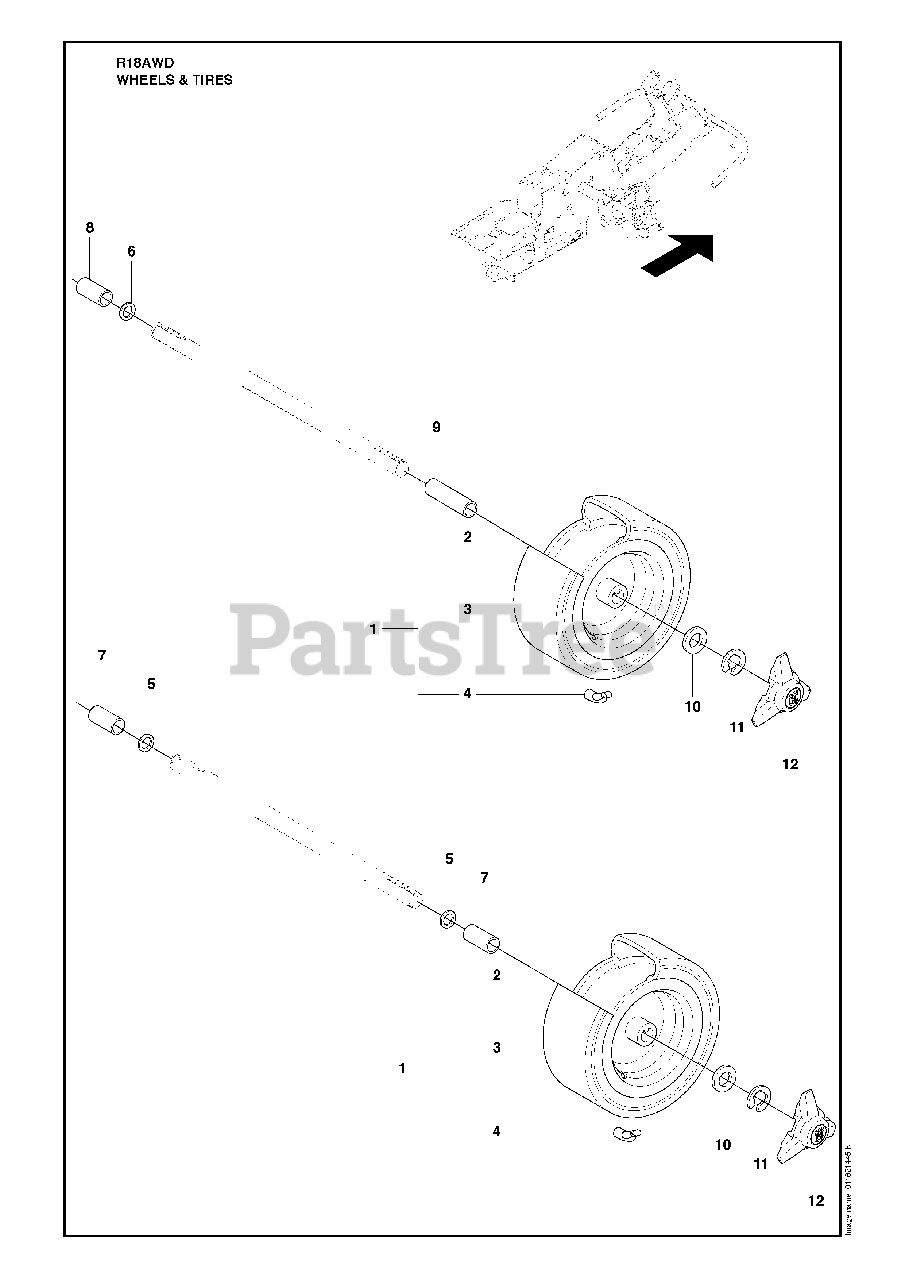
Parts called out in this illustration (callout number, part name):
3	TIRE
4	VALVE
7	SPACE SLEEVE
11	RETAINING RING
